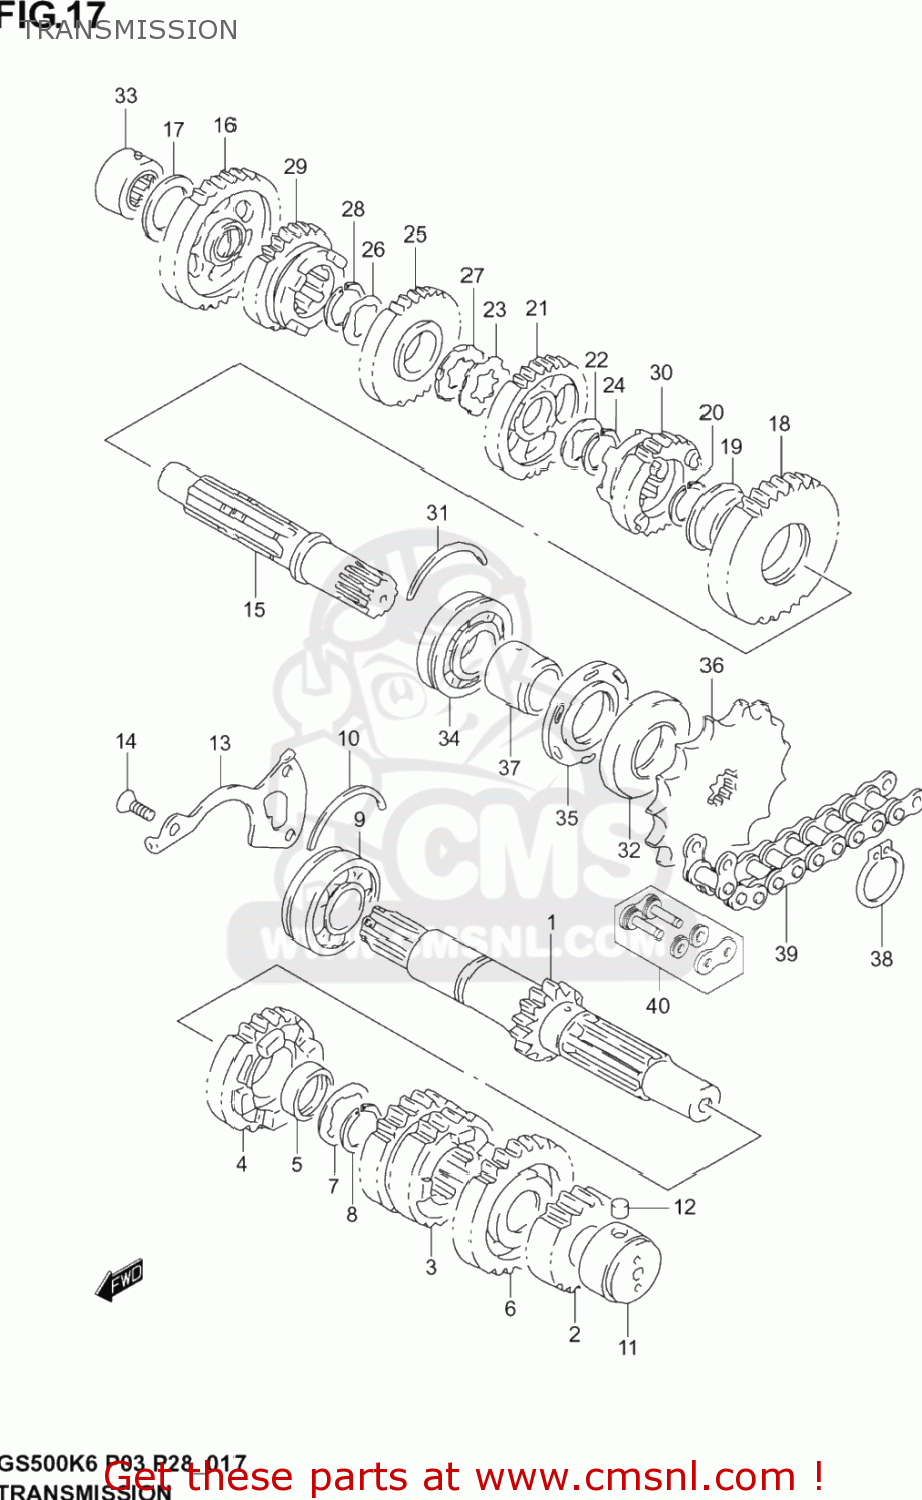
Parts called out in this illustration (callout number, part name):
1	SHAFT,COUNTER
2	GEAR,2ND DRIVE(NT:18)
3	GEAR,3RD & 4TH
4	GEAR,5TH DRIVE(NT:26)
5	BUSH
6	GEAR,6TH DRIVE
7	SHIM(25X34X1)
8	CIRCLIP
9	BEARING(25X62X17)
10	C RING
11	BEARING(20X34X20)
12	PIN
13	PLATE,COUNTERSHAFT BEARING
14	SCREW(6X16)
15	SHAFT,DRIVE
16	GEAR,1ST DRIVEN
17	SHIM(20X34X1)
18	GEAR,SECOND DRIVEN (NT:32)
19	BUSH
20	CIRCLIP
21	GEAR,3RD DRIVEN
22	WASHER,LOCK
23	WASHER,LOCK
24	CIRCLIP
25	GEAR,4TH DRIVEN
26	WASHER,LOCK
27	WASHER
28	CIRCLIP
29	GEAR,5TH DRIVEN(NT:25)
30	GEAR,6TH DRIVEN(NT:23)
31	C RING
32	SEAL,OIL(32X62X7)
33	BEARING(20X34X17)
34	BALL BEARING 25X62X17
35	SEAL,OIL(32X62X5.5)
36	SPROCKET,ENGINE(16T)
37	SPACER,ENGINE SPROCKET
38	CIRCLIP
39	CHAIN, DRIVE (DID520VM, 110LE
40	JOINSET, CHAIN
